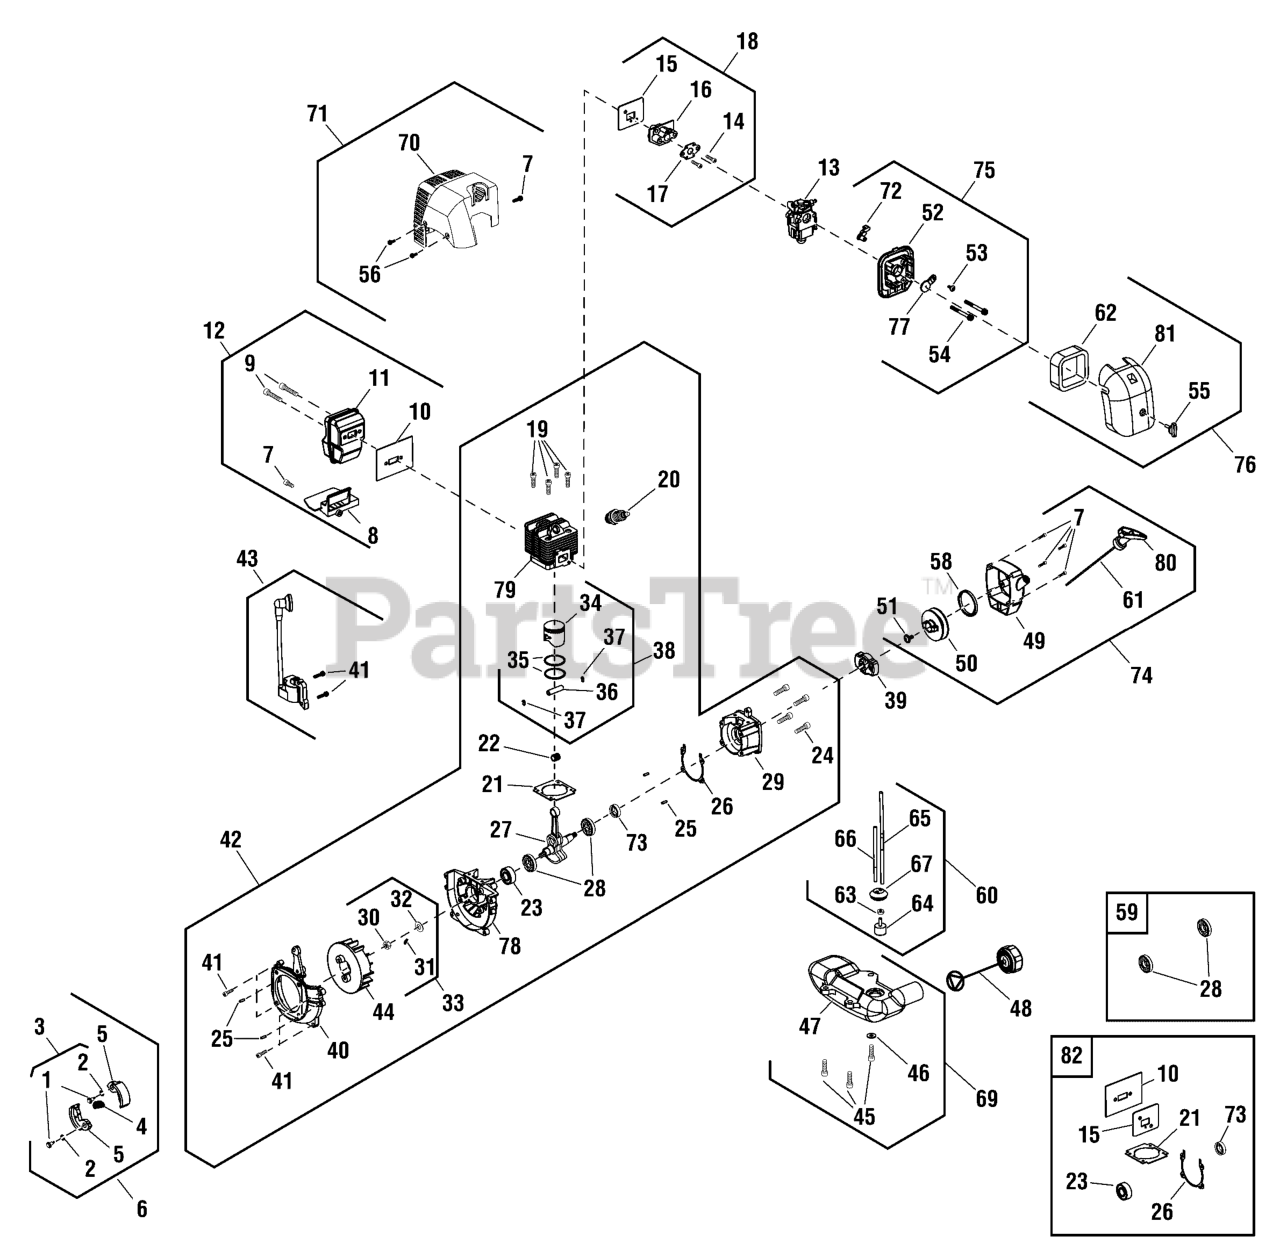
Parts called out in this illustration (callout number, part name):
2	* WASHER, Clutch
3	KIT, Hardware, Bolts & Washers
4	* SPRING, Clutch
5	* SHOE, Clutch
6	CLUTCH & SPRING ASSEMBLY
8	* HEAT SHIELD
10	* SHIELD, Muffler
11	* MUFFLER
12	MUFFLER ASSEMBLY
13	CARBURETOR
15	* GASKET, Inlet Manifold
16	* INLET MANIFOLD
17	* GASKET, Carburetor
18	INTLET MANIFOLD ASSEMBLY
20	SPARK PLUG
21	* GASKET, Cylinder
26	* GASKET, Crankcase
27	* CRANK SHAFT
29	* CRANK CASE, Rear
33	KIT, Hardware, Flywheel Securing
34	* PISTON
35	* RING, Piston
36	* PIN, Piston
37	* CIRCLIP, Piston Pin
38	PIN & GUDGEON PIN ASSEMBLY
39	CUP, Starter Pulley, Inner
40	* COVER, Flywheel
42	SHORT ENGINE ASSEMBLY
43	IGNITION UNIT
44	MAGNETO FLYWHEEL
47	* FUEL TANK
48	CAP, Fuel
49	* HOUSING, Starter
50	* SPOOL, Starter
52	* AIR CLEANER BODY
55	* KNOB, Screw
58	* COIL, Starter Spring
59	KIT, BALL BEARING, Main, 6001
60	KIT, Fuel Line & Filter
61	* SPOOL, Starter
62	FILTER, Air
64	FILTER, Fuel
65	* TUBE, Fuel, Inlet
66	* TUBE, Fuel, Outlet
67	* GROMMET, Hose
69	KIT, Fuel Tank, With Hardware
70	* HOUSING, Starter
71	ENGINE COVER ASSEMBLY, Red
72	* LEVER, Chock
74	STARTER ASSEMBLY, Red
75	THROTTLE PLATE ASSEMBLY, Red
76	AIR FILTER ASSEMBLY, Black
77	* CHOKE VALVE
78	* CRANK CASE, Front
79	CYLINDER
80	* HANDLE, Starter
81	* COVER, Air Cleaner
82	KIT, Gasket
